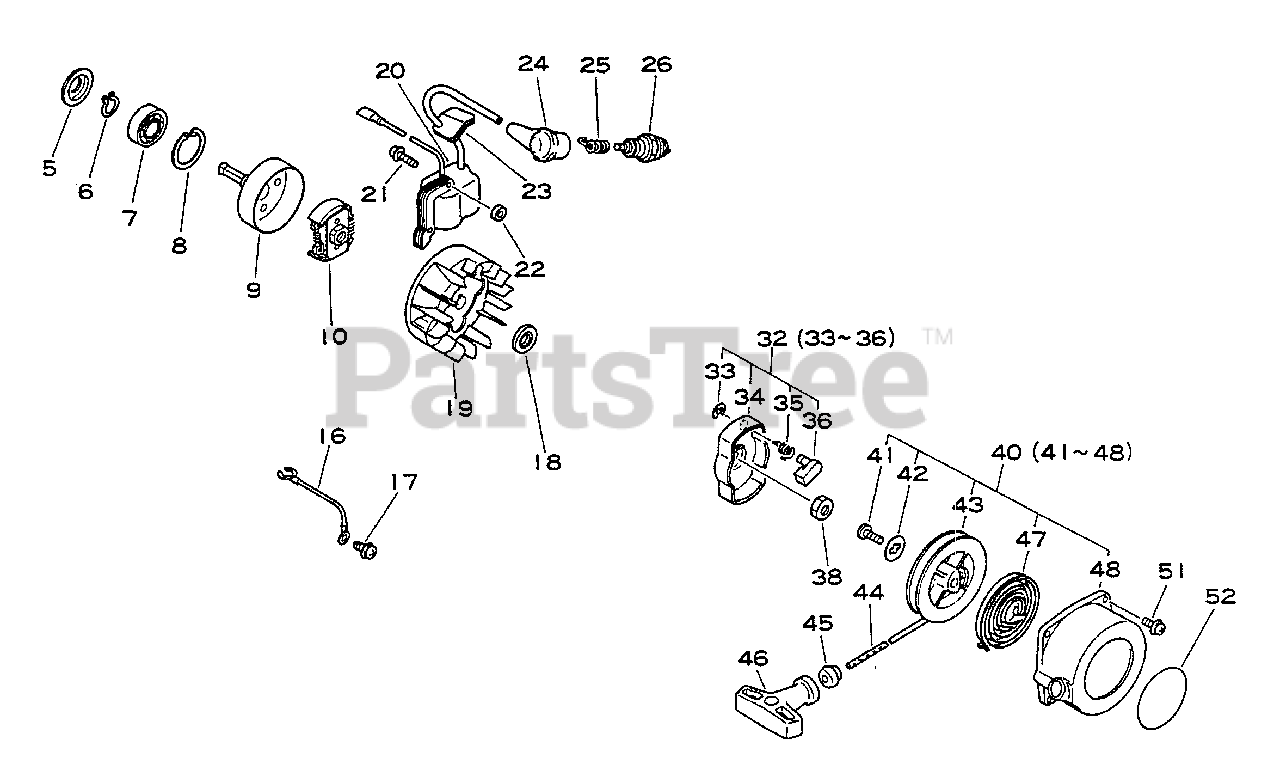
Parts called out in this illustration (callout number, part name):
5	RETAINER, PIPE
6	RING, RETAINING - 12
7	BEARING, BALL - 6201
8	RING, RETAINING - 32
9	DRUM, CLUTCH
10	CLUTCH ASSY
16	LEAD - GROUND
17	SCREW - 5X10
18	WASHER
19	FLYWHEEL
20	COIL, IGNITION
21	SCREW - 4X22
23	COVER, DUST
24	CAP, SPARK PLUG
25	TERMINAL, SPARK PLUG CAP
26	SPARK PLUG -- CJ-7Y
32	STARTER PAWL ASSY
33	RING, RETAINING - 6
34	CATCHER, PAWL
35	SPRING, RETURN
36	PAWL, STARTER
40	STARTER ASSY
42	WASHER
43	REEL, ROPE
44	ROPE, STARTER - 3X890
45	GUIDE, ROPE
46	GRIP, STARTER
47	SPRING, REWIND
48	CASE, STARTER
51	SCREW - 4X16
52	LABEL - ECHO
